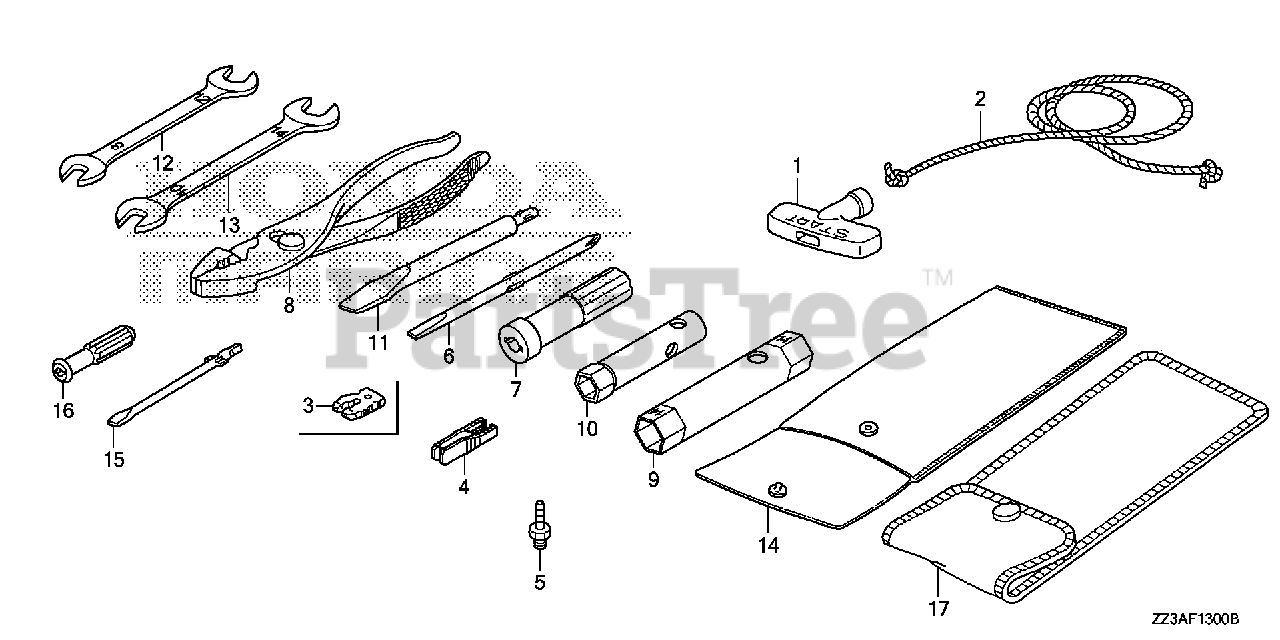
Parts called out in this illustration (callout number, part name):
1	KNOB, RECOIL SRARTER
2	ROPE, RECOIL STARTER (1300MM)
4	PULLER, MINI FUSE (SUMITOMO)
5	NIPPLE, SENSOR
6	SCREWDRIVER (NO.2 PHILLIPS -)
7	GRIP
8	PLIERS (135) (RIKEN)
9	WRENCH, PLUG
10	WRENCH, BOX (10MM)
11	SCREWDRIVER, CHECK BOLT
12	SPANNER (8X12)
13	SPANNER (10X14)
14	BAG, TOOL
15	DRIVER 3, MINUS SCREW (NO.2)
16	GRIP, SCREW DRIVER
17	BAG, TOOL (160MM)
